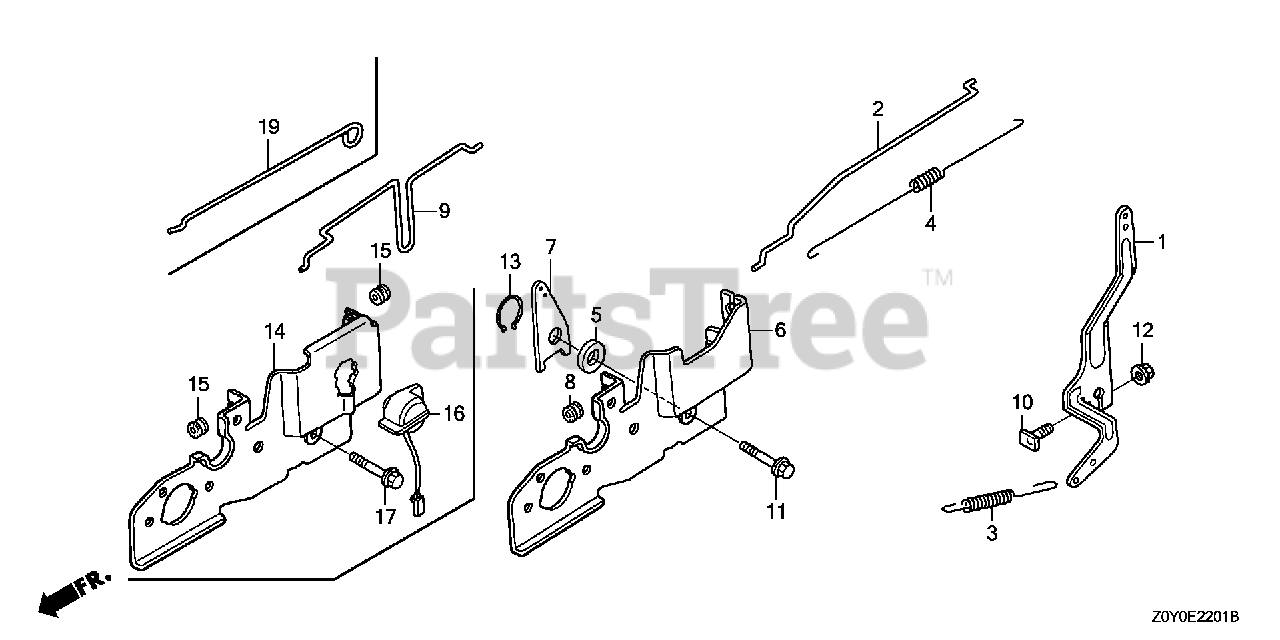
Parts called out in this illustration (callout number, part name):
1	ARM, GOVERNOR
2	ROD, GOVERNOR
3	SPRING, GOVERNOR
4	SPRING, THROTTLE RETURN
10	BOLT, GOVERNOR ARM
12	NUT, FLANGE (6MM)
14	BASE, CONTROL
15	GROMMET, CHOKE ROD
16	SWITCH ASSY., ENGINE STOP
17	BOLT, FLANGE (6X45)
19	ROD, CHOKE
